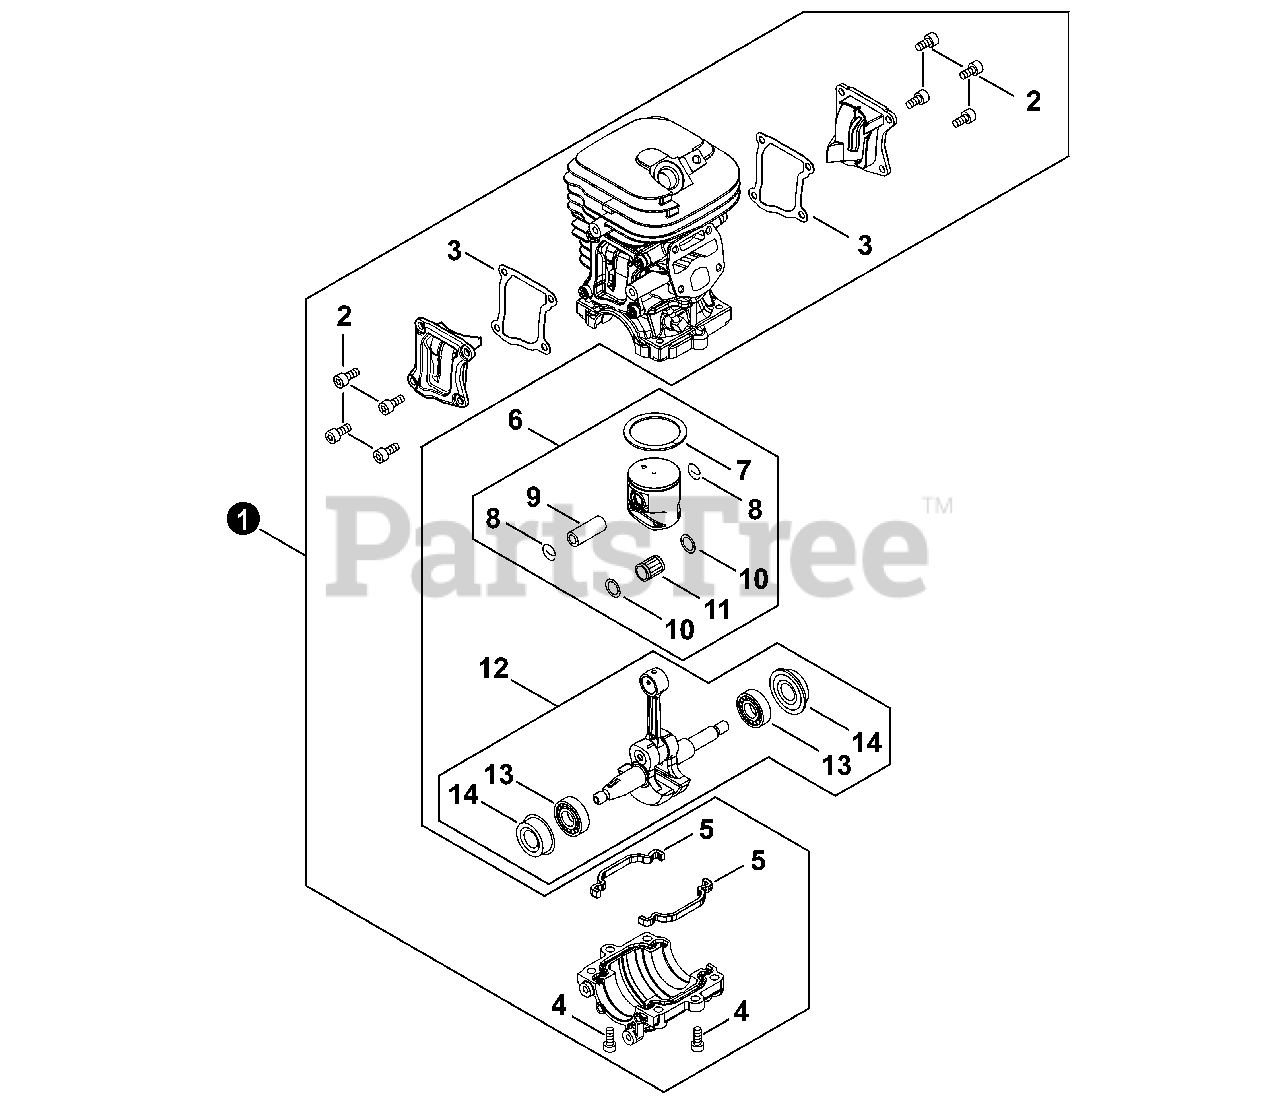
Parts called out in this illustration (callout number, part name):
1	CRANKCASE SET
2	BOLT, TORX 4
4	BOLT, TORX 5×16
5	SEAL
6	PISTON KIT
7	RING, PISTON
8	RING, SNAP Ø10
9	PIN, PISTON
10	WASHER, THRUST
11	BEARING, NEEDLE
12	CRANKSHAFT ASSY
13	BEARING, BALL 6202
14	SEAL, OIL
